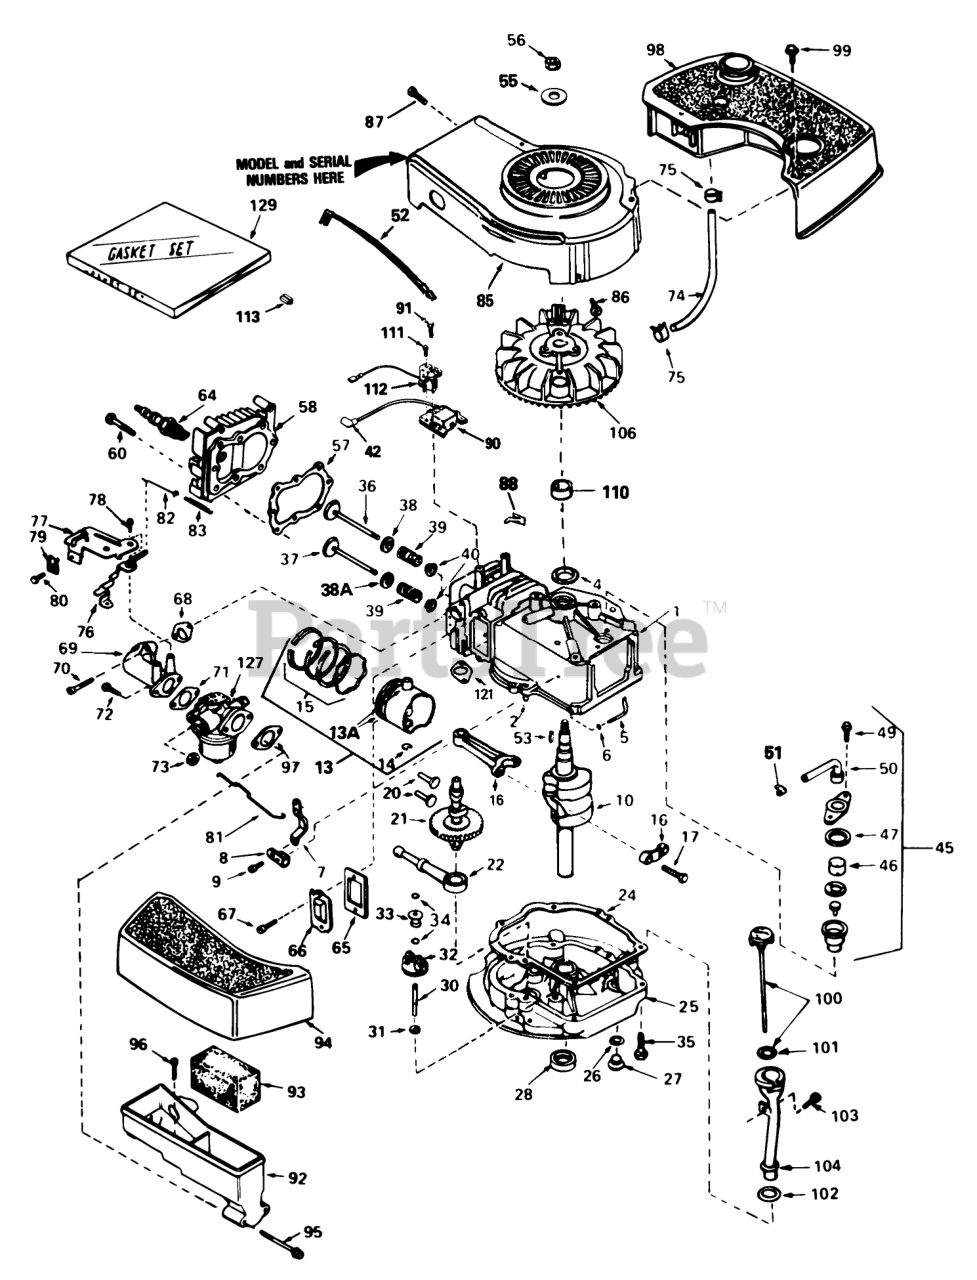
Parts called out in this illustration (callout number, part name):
1	Cylinder Assembly (Incl. Ref. #2 & 4
2	Pin-Dowel
4	Seal-Oil
5	Rod-Governor (Incl. Ref. #6)
6	Washer-Flat
7	Governor Lever
8	Clamp-Lever, Governor
9	Screw
10	Crankshaft
13	Piston-Pin & Ring Assy. (Std.) (Incl. Ref. #13A, 14 & 15)
13	Piston-Pin & Ring Assembly (.010 oversize) (Incl. Ref. #13A, 14 & 15)
13	Piston-Pin & Ring Assembly (.020 oversize) (Incl. Ref. #13A, 14 & 15)
13A	Piston & Pin Assembly (Std.) (Incl. Ref. #14)
13A	Piston & Pin Assembly (.010 oversize) (Incl. Ref. #14)
13A	Piston & Pin Assembly (.020 oversize) (Incl. Ref. #14)
14	Ring-Retaining, Piston Pin
15	Ring Set (Std.)
15	Ring Set (.020" OS)
15	Ring Set (.010" OS)
16	Rod Assembly-Connecting (Incl. Ref. #17)
17	OA Bolt-Connecting Rod
20	Lifter-Valve
21	Camshaft(Mech.Comp. Release)
22	Oil Pump ASM
24	Gasket
25	Flange Assembly-Mounting (Incl. Ref. #26, 27, 28 & 30)
26	Gasket-Oil Drain
27	Plug Oil Drain
28	Seal Oil
30	Shaft-Governor
31	Washer-Flat
32	GearAssembly-Governor (Incl. Ref. #31)
33	Spool-Governor
34	Ring-Retaining
35	Screw (1/4-20 x 1-1/4)
36	Valve-Intake (Std.)(Incl. Ref. #40)
36	Valve-Intake (1/32" oversize)(Incl. Ref. #40)
37	Valve-Exhaust (Std.)(Incl. Ref. #40)
37	Valve-Exhaust (1/32" oversize)(Incl. Ref. #40)
38	Seal Assy., Intake
38A	Cap-Upper Valve Spring
39	Spring-Valve
40	Cap-Valve, Spring
42	Cover-Spark Plug
45	Breather Assembly (Incl. Ref. #46 thru 51)
46	Element-Breather
47	Gasket-Breather
49	Screw (10-24 x 9/16)
50	Tube, Breaker
51	Clip, Breather
52	Wire-Ground
53	Key-Flywheel
55	Washer-Belleville
56	Nut-Flywheel
57	63573 GIL 42 SNWTHW
58	Head-Cylinder
60	Screw (5/16-18x1-1/2)
64	Plug, Spark (Autolite 458, Champion J-19LM or equiv.)
65	Gasket-Breather
66	Cover-Valve
68	Gasket-Intake
69	Pipe-Intake (Incl. Ref. #68)
70	Screw (1/4-20 x 1)
71	Gasket-Carburetor
72	Screw (1/4-28 x 7/8)
73	Nut and Lock Washer (1/4-28)
74	Line-Fuel
75	Clamp-Line, Fuel
76	Lever Control
77	Control Assembly-Speed (Incl. Ref. #76 & 78)
78	Screw, Hex Washer Hd Shoulder Self-Tap
79	Conduit
80	Screw (10-32 x 3/8)
81	Link-Throttle
82	Link Governor Spring
83	Spring Governor
85	Housing-Blower
86	Screw (1/4-20x19/32)
87	Screw (10-24 x 9/16)
88	Clip-Wire
90	Solid State
91	Screw
92	Body Air Cleaner
93	Filer, Air
94	Cove, Air Cleaner
95	Screw Fil Hd.
96	Screw, Hex Washer Hd Shoulder Self-Tap
97	Gasket-Air Cleaner
98	Tank-Fuel
99	Screw (10-32 x 35/64)
100	Dipstick-Oil (Incl. Ref. #101)
103	Screw (10-32 x 1/2)
104	Tube-Oil Fill
106	Flywheel
111	Screw (8-32x27/64)
112	Coil, Alternator
113	Connector-Body
121	Gasket Exhaust
127	Carburetor (Incl. Ref. #71)
129	Gasket Set (Incl. Items Marked )
